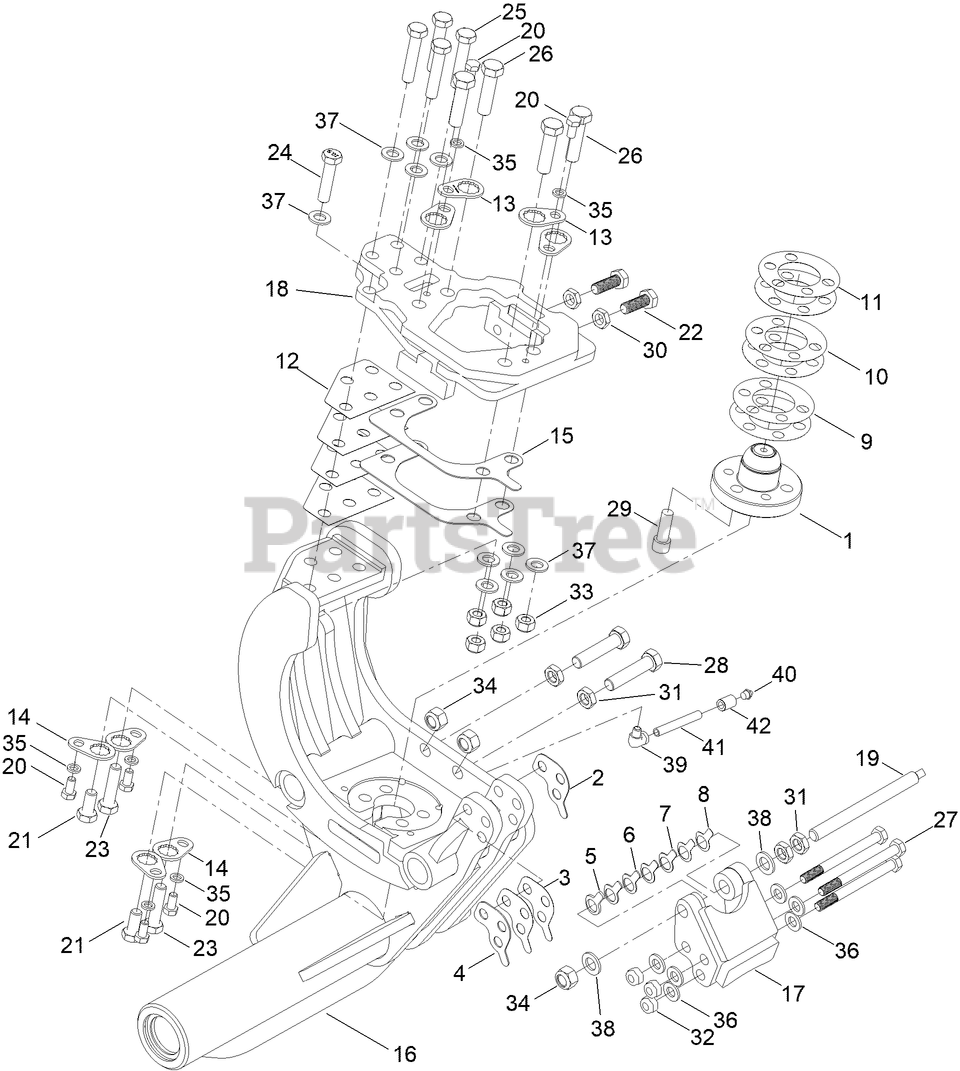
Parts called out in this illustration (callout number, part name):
1	PIN-KING, TRACKS
2	DIRECTION LIMITOR SHIM 18 GA.
3	DIRECTION LIMITOR SHIM 26 GA.
4	DIRECTION LIMITOR SHIM 16 GA.
5	SHIM 11 GA.
6	SHIM 16 GA.
7	SHIM 18 GA.
8	SHIM 26 GA.
9	SHIM KING PIN .005"
10	SHIM KING PIN .010"
11	SHIM KING PIN .015"
12	TOP MOUNTING PLATE SHIM 26 GA.
13	M16 BOLT LOCKING PLATE
14	M14 BOLT LOCKING PLATE
15	SHIM 16 GA.
16	FRONT LEFT AND REAR RIGHT BRACKET ASM
17	FRONT LEFT AND REAR RIGHT DIR LIMITOR
18	FRONT LEFT AND REAR RIGHT TOP PLATE
19	ROD-THREADED
20	SCREW-HH
21	SCREW-HH
22	SCREW-HH
23	SCREW-HH
24	SCREW-HH
25	SCREW-HH
26	SCREW-HH
27	SCREW-HH
28	SCREW-HH
29	SCREW-HSH
30	NUT-HEX
31	NUT M16 THIN
32	NUT-HEX, LOCK
33	NUT-METRIC
34	NUT-METRIC
35	WASHER-FLAT
36	WASHER-FLAT
37	WASHER-PLAIN
38	WASHER-FLAT
39	ELBOW
40	FITTING-GREASE
41	NIPPLE
42	COUPLING-PIPE
